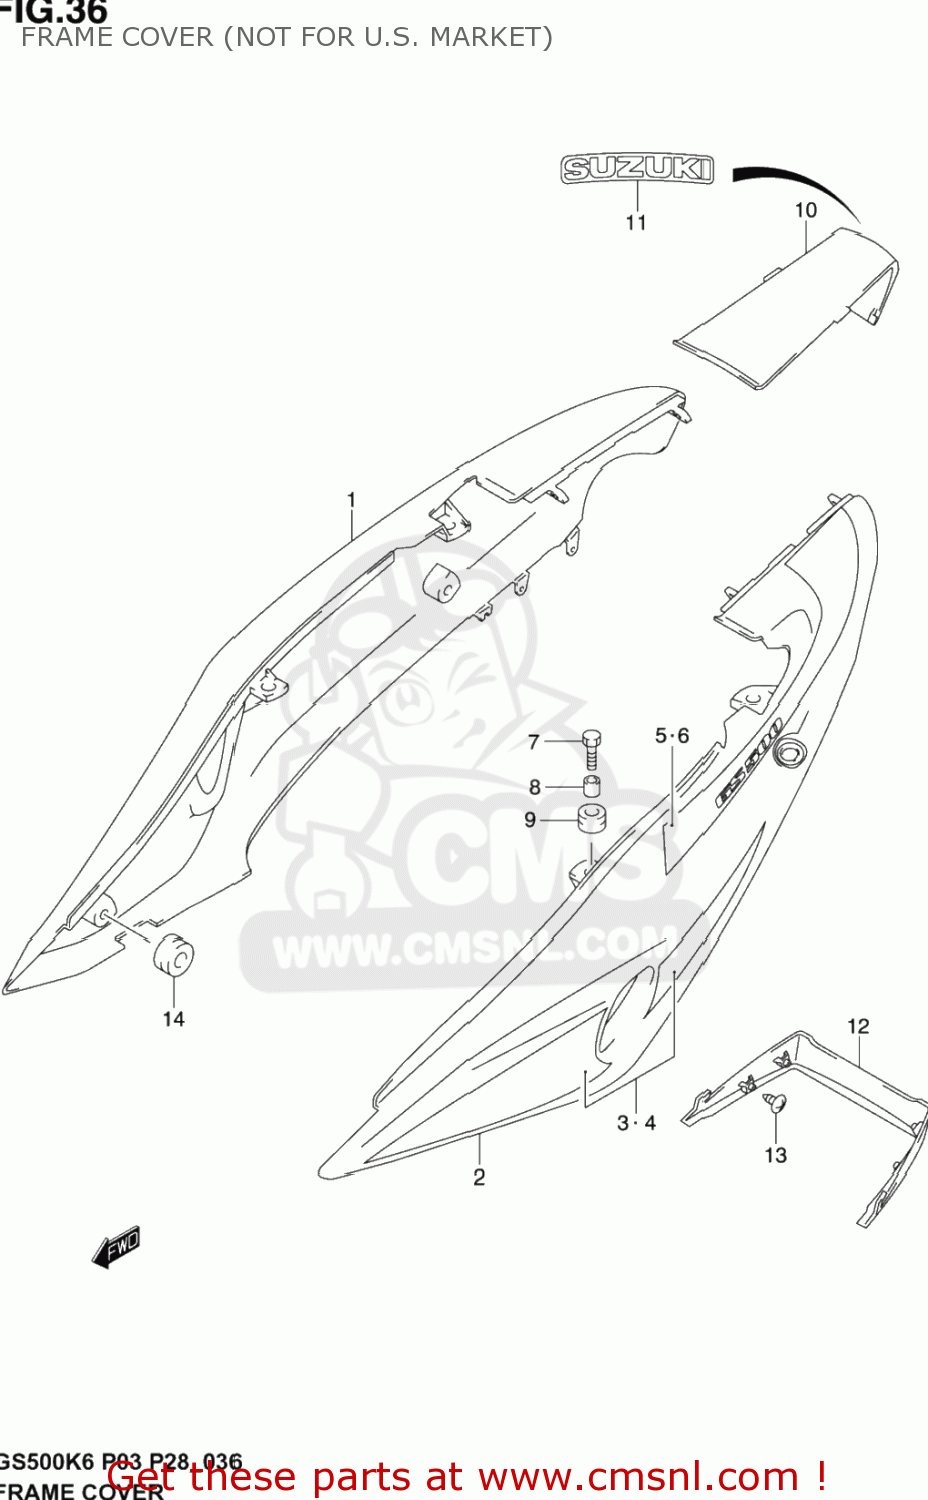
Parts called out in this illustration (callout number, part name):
1	COVER,FRAME RH
2	COVER,FRAME LH
3	EMBLEM ASSY
4	EMBLEM ASSY
5	BOLT
5A	WASHER
6	SPACER(6.5X9X9)
7	CUSHION
8	COVER,CENTER
9	EMBLEM (BLACK)
10	COVER LOWER
11	SCREW
12	CUSHION
